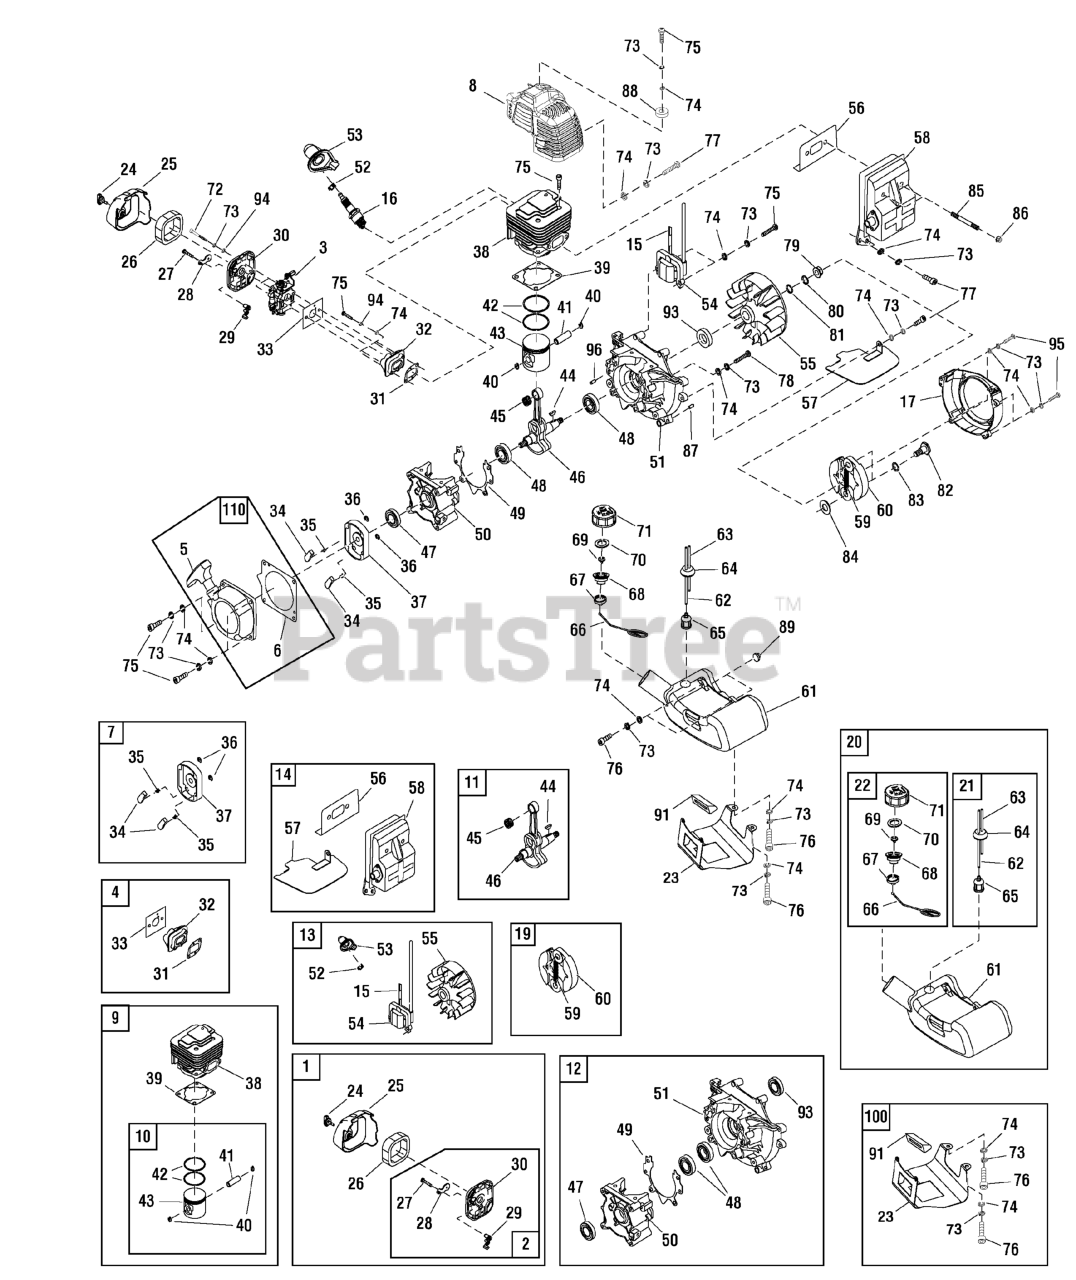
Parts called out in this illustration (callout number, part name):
1	KIT, Air Cleaner Assembly, Complete
2	KIT, Air Cleaner Assembly, Inner
3	CARBURETOR
4	KIT, Admitting Pipe Assembly
5	STARTER, Rewind
6	PAD, Starter
7	KIT, Start Reel Assembly
8	SHROUD
9	KIT, Cylinder Assembly
10	KIT, Piston Assembly
11	KIT, Crank Shaft Assembly
12	KIT, Cylinder Case Assembly
13	KIT, Magneto Assembly
14	KIT, Muffler Assembly
16	SPARK PLUG
17	COVER, Fan
19	KIT, Expander Assembly
20	KIT, Fuel Tank Assembly
21	KIT, Fuel Line Assembly
22	KIT, Fuel Cap Assembly
23	BRACKET, Tank
25	COVER, Cleaner, Outer
26	FILTER
27	SCREW, Self Tapping, ST4.2 x 12
28	CHOKE VALVE
29	HANDLE, Choke Valve
30	COVER, Cleaner, Inner
31	GASKET, Admitting Pipe
32	ADMITTING PIPE
33	GASKET, Carbuetor
34	STARTER CINCH
35	SPRING, Starter
36	RING, Retainer
37	STARTER BOX
38	CYLINDER
39	GASKET, Cylinder
40	RING, Pin Retain
41	PIN, Piston
42	RING, Piston
43	PISTON
44	KEY, 3 x 5 x 13
45	BEARING, Needle
46	CRANKSHAFT
47	SEAL, Oil, 11.7 x 22 x 7
48	BEARING, 6201/P6
49	GASKET, Crank Case
50	CRANK CASE, Rear
51	CRANK CASE, Front
52	CLIP, Spark Plug
53	BOOT, Spark Plug
54	MAGNETO COIL
55	FLY WHEEL
56	GASKET, Muffler
57	CLAPBOARD
58	MUFFLER
59	SPRING, Extension
60	EXPANDER, Complete
61	TANK, Fuel
62	PIPE, Fuel
63	PIPE, Soft PVC
64	PLUG, Fuel Line
65	FILTER, Fuel
66	CHAIN
67	COVER, End
68	LID, Fuel Tank, Inner
69	INLET
70	GASKET
71	LID, Fuel Tank
72	BOLT, M5 x 50
73	WASHER, Spring, 5
74	WASHER, Flat, 5
75	BOLT, M5 x 20
76	BOLT, M5 x 16
77	BOLT, M5 x 12
78	BOLT, M5 x 30
79	NUT, M8
80	WASHER, Spring, 8
81	WASHER, Flat, 8
82	SCREW, Shaft
83	WASHER, Wave
84	WASHER, B
85	BOLT, Muffler
86	NUT, M6
87	PIN, Cylindrical, B4 x 10
88	GASKET
89	PLUG, Rubber
91	COVER, Rubber
93	SEAL, Oil, 30 x 14.7 x 7
94	WASHER, Spring, 5
95	BOLT, M5 x 25
96	PIN, Cylindrical, B5 x 12
100	KIT, Tank Bracket Assembly
110	KIT, Starter Assembly
